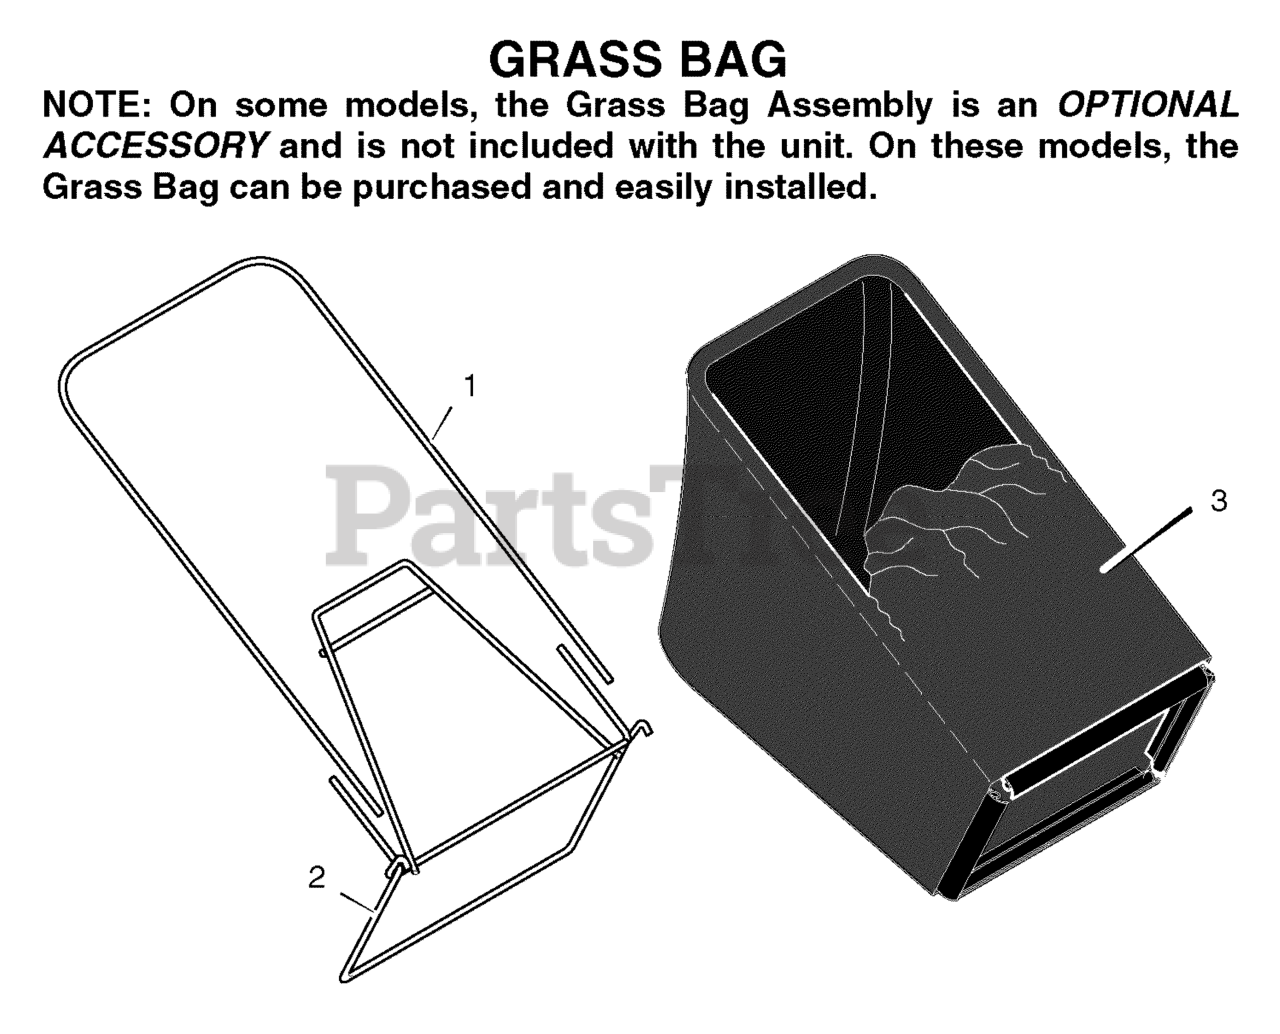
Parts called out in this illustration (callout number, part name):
1	Frame, Top
2	Frame Assembly
3	Bag, Cloth - Black
